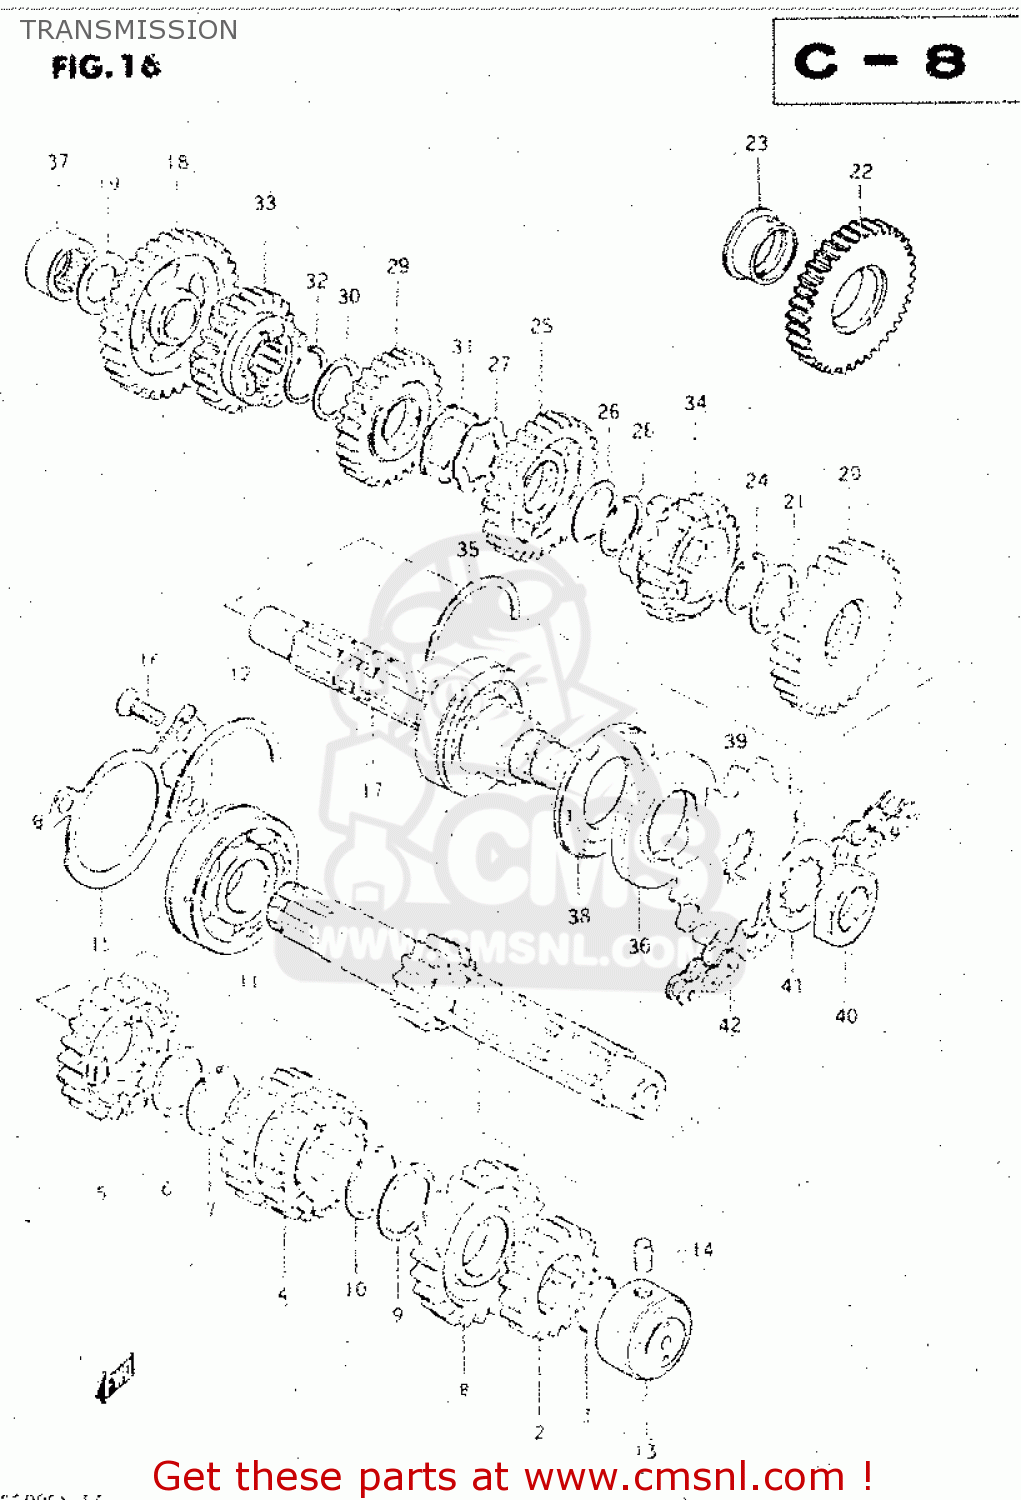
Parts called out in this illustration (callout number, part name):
1	SHAFT,COUNTER
2	GEAR,SECOND DRIVE
3	RING,SNAP
4	GEAR,THIRD DRIVE
5	GEAR,FIFTH DRIVE
6	WASHER
7	CIRCLIP
8	GEAR,SIXTH DRIVE
9	WASHER,LOCK
10	CIRCLIP
11	BEARING(25X62X17)
12	C-RING
13	BEARING
14	PIN
15	PLATE,COUNTERSHAFT BEARING
16	SCREW
17	SHAFT,DRIVE
18	GEAR,FIRST DRIVEN
19	WASHER
20	GEAR,SECOND DRIVEN
21	WASHER
22	GEAR,SECOND DRIVEN
23	BUSHING
24	CIRCLIP
25	GEAR,THIRD DRIVEN
26	WASHER,LOCK
27	WASHER,LOCK
28	CIRCLIP
29	GEAR,FOURTH DRIVEN
30	WASHER,LOCK
31	WASHER
32	CIRCLIP
33	GEAR,FIFTH DRIVEN
34	GEAR,SIXTH DRIVEN
35	C-RING
36	SEAL,OIL(32X62X7)
37	ROLLER BEARING (20X34X1
38	SEAL,OIL(32X62X5.5)
39	SPROCKET,ENGINE
40	NUT
41	WASHER
42	CHAIN ASSEMBLY,DRIVE
